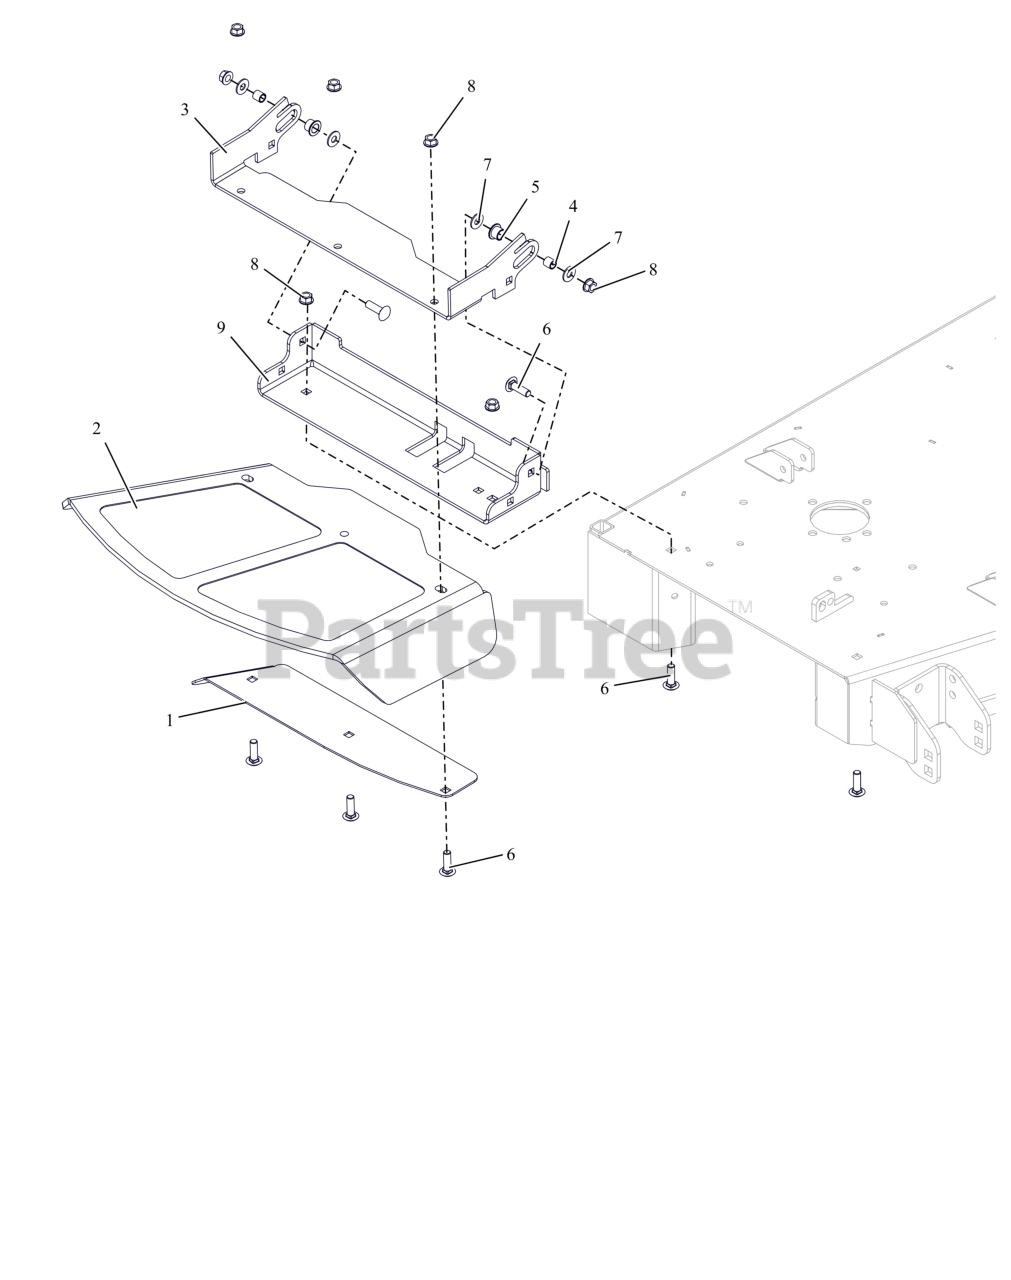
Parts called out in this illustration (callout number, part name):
1	48-60 DISCH CHUTE CLMP PLT-RED
2	CHUTE, FORMED RUBBER DISCHARGE
3	BRKT, CHUTE MOUNT (RED)
4	SPCR, .385X.500X.350
5	BSHG, FLANGED .50X.625X.50X.062
6	BLT,RHSSN .38-16X1.25 G5 ZCC
7	WSHR, HDND 0.375X0.875X0.064 ZCC
8	NUT-LK-CTR-FLG .375-16 GF ZCC
9	BASE, DISCHARGE CHUTE MTG BRKT (RED)
